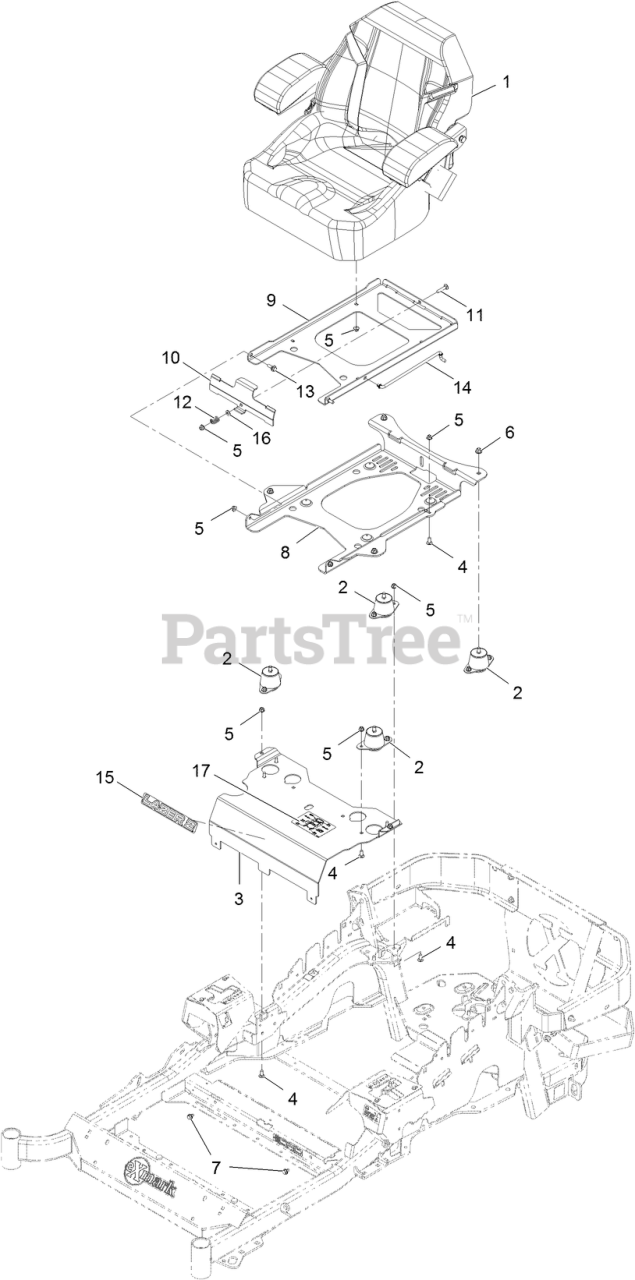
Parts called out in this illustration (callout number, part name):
1	SEAT-EXMARK STANDARD
2	ISOLATOR-SEAT
3	Panel-Front, Seat Mount
4	SCREW-CARR
5	NUT-HF, NI
6	NUT-HF, NI
8	PLATE-TILT, SEAT SUPPORT
9	PLATE-FRAME, SEAT
10	PLATE-LATCH, SEAT
11	BOLT-CARR
12	SPRING-COMPRESSION
13	SCREW-SHOULDER
14	ROD-PROP
15	DECAL, LAZER MODEL
16	WASHER-PLAIN
17	DECAL-SERVICE AID
